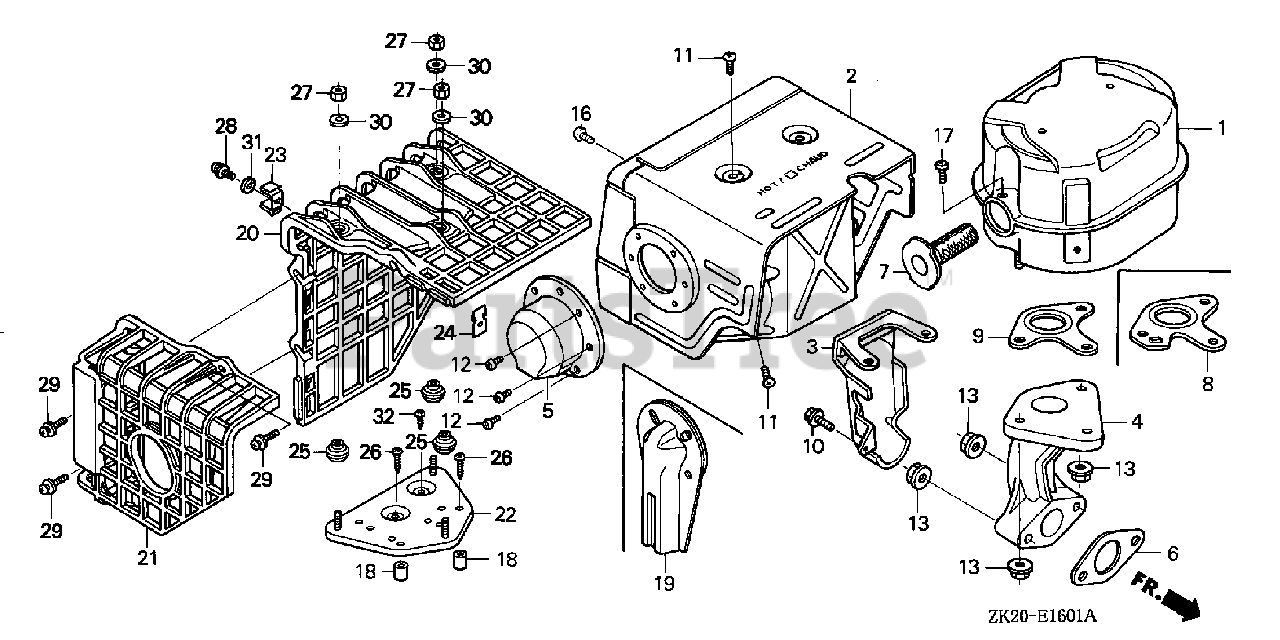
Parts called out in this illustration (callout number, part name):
1	MUFFLER
2	PROTECTOR, MUFFLER
3	PROTECTOR, EX. PIPE
4	PIPE, EX.
6	GASKET, EX. PIPE
6	GASKET, EX. PIPE (WACKER)
9	GASKET, MUFFLER
10	BOLT, FLANGE (6X12) (CT200)
11	SCREW, TAPPING (5X8)
13	NUT, FLANGE (8MM)
